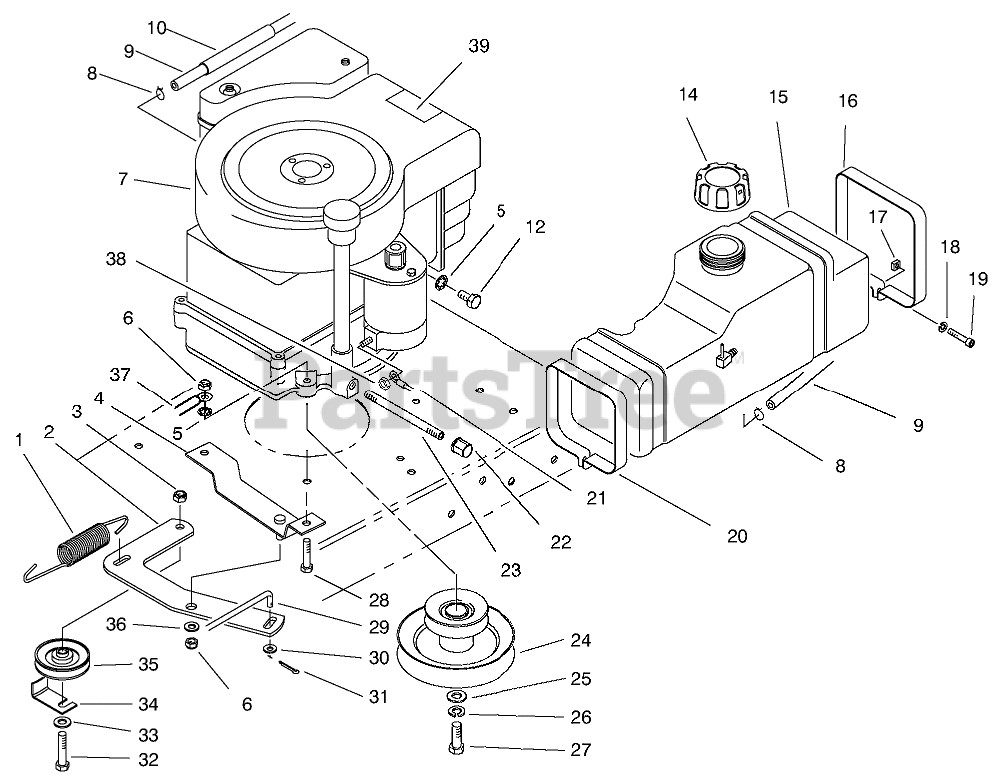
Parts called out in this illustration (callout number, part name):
1	SPRING-TRACTION
2	BRKT-TRACTION PIVOT
3	NUT-LOCK, NI
4	TRACT SUPT BRKT WA (BLACK)
5	WASHER-LOCK, INTERNAL
6	NUT-LOCK, NI
7	Engine-11.5 H.P.
8	CLAMP-HOSE
9	HOSE - FUEL
10	SUPPORT-FUEL LINE
12	SCREW-HWHTF
14	GAS CAP ASM
15	TANK-5 QT GAS
16	RETAINER-FRT TANK
17	NUT-SQUARE
18	WASHER-LOCK
19	SCREW-HSH
20	RETAINER-REAR TANK
21	WIRE ASM
22	CAP-PIPE
23	NIPPLE
24	PULLEY-ENGINE
25	WASHER-FLAT
26	WASHER-LOCK
27	SCREW-HH
28	SCREW-HH
29	ROD-TRACTION
30	WASHER-FLAT
31	PIN-COTTER
32	SCREW-HH
33	WASHER-FLAT
34	RETAINER-BELT
35	PULLEY-IDLER
36	WASHER-FLAT
37	WIRE ASM
38	NUT-JAM
39	DECAL - ENGINE
